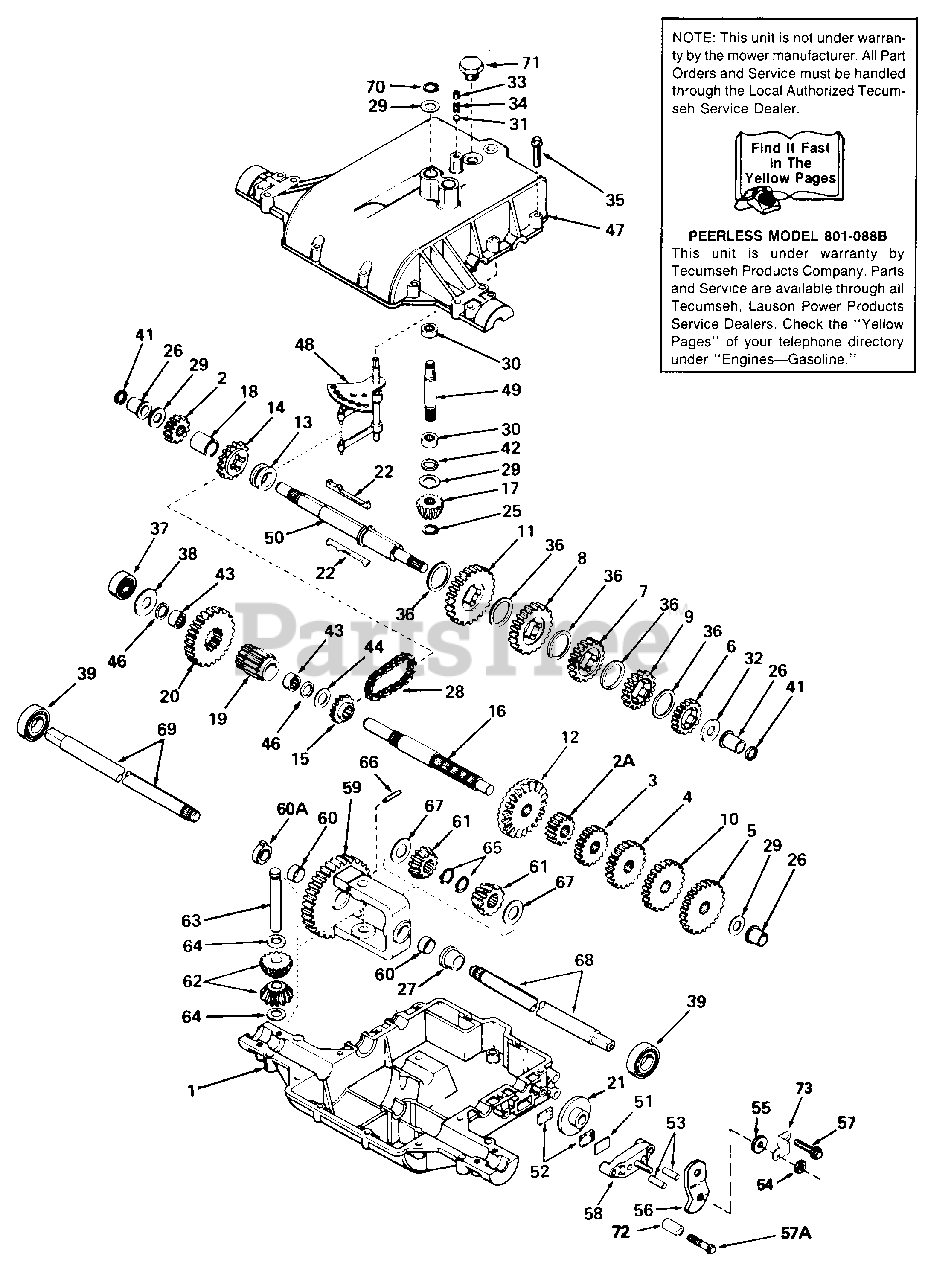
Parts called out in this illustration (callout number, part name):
1	Case, Transaxle
2	Gear, Spur (15 teeth)
2A	Gear, Spur (12 teeth)
3	Gear, Spur (20 teeth)
4	Gear, Spur (25 teeth)
5	Gear, Spur (30 teeth)
6	Gear, Spur (20 teeth)
7	Gear, Spur (25 teeth)
8	Gear, Spur (30 teeth)
9	Gear, Spur (22 teeth)
10	Gear, Spur (28 teeth)
11	Gear, Spur (37 teeth)
12	Gear, Bevel (42 teeth)
13	Collar, Shift
14	Sprocket (18 teeth)
15	Sprocket (9 teeth)
16	Shaft, Counter
17	Bevel Pinion, Input
18	Spacer
19	Pinion, Output
20	Gear, Output
21	Disk, Brake
22	Key
25	Ring, Retaining
26	Bushing, Flanged
27	Bushing, Flanged
28	Chain, Roller (No. 41 Chain, 24 Links)
29	Washer, Thrust
30	Bearing, Needle
31	Ball, Steel
32	Washer, Thrust
33	Screw, Set, 3/8-16 x 3/8
34	Spring
35	Screw, Hex Hd. Thread Forming, 1/4-20 x 11/4
36	Washer, Thrust
37	Bearing, Ball
38	Washer, Flat
39	Bearing, Ball
41	Ring, Square Cut
42	Ring, Square Cut
43	Bearing, Needle
44	Washer, Flat
46	Ring, Square Cut
47	Cover, Transaxle
48	Rod & Fork Ass'y., Shift
49	Shaft, Input
50	Shaft, Brake
51	Plate, Brake Pad
52	Pad, Brake
53	Pin, Dowel
54	Locknut, 5/16-24
55	Washer, Flat
56	Lever, Brake
57	Screw, Hex Hd. Thread Forming, 1/4-20 x 11/4
57A	Screw, Hex Hd. Thread Forming, 1/4-20 x 21/4
58	Holder, Brake Pad
59	Gear Ass'y., Differential
60	Bushing
60A	Bushing
61	Gear, Bevel
62	Pinion, Bevel
63	Pin, Drive
64	Washer, Thrust
65	Ring, Retaining
66	Pin, Roll
67	Washer, Thrust
68	Axle (15-1/4" Long)
69	Axle (13-3/8" Long)
70	Ring, Retaining
71	Plug, Hex Hd., 9/16-18 Thread
72	Spacer
73	Bracket, Brake Lever
